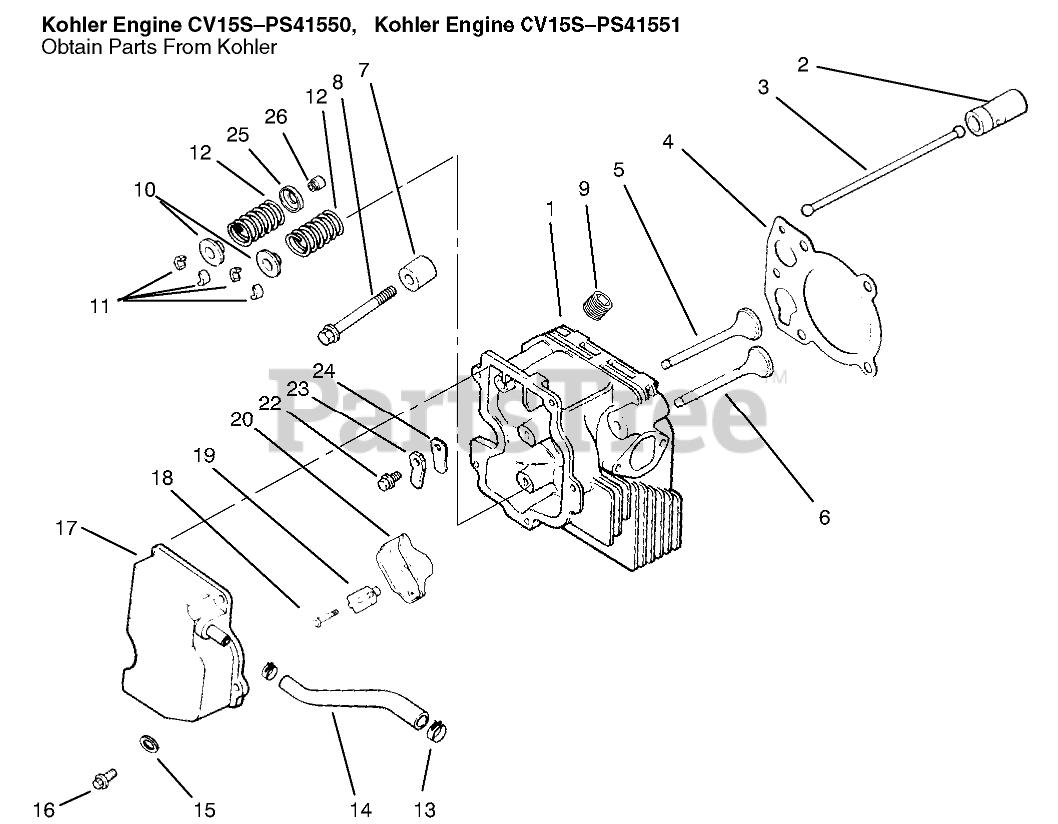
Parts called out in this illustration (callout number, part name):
1	Cylinder Head
2	Lifter-Valve
3	Rod-Push
4	Gasket-Cylinder Head
5	Valve-Intake STD
5	Valve-Intake .25
6	Valve-Exhaust STD
6	Valve-Exhaust .25
7	Spacer-Head Bolt
8	Screw M10x1.5x80
9	Plug
10	Cap-Spring, Valve
11	Retainer Kit
12	Spring-Valve
13	Clamp
14	Hose-Breather
15	Washer
16	Screw
17	Cover-Valve w/Nipple
19	Pivot-Rocker Arm
20	Arm-Rocker
22	Screw
23	Retainer-Reed
24	Reed-Breather
25	Retainer-Spring
26	Seal-Stem, Valve
